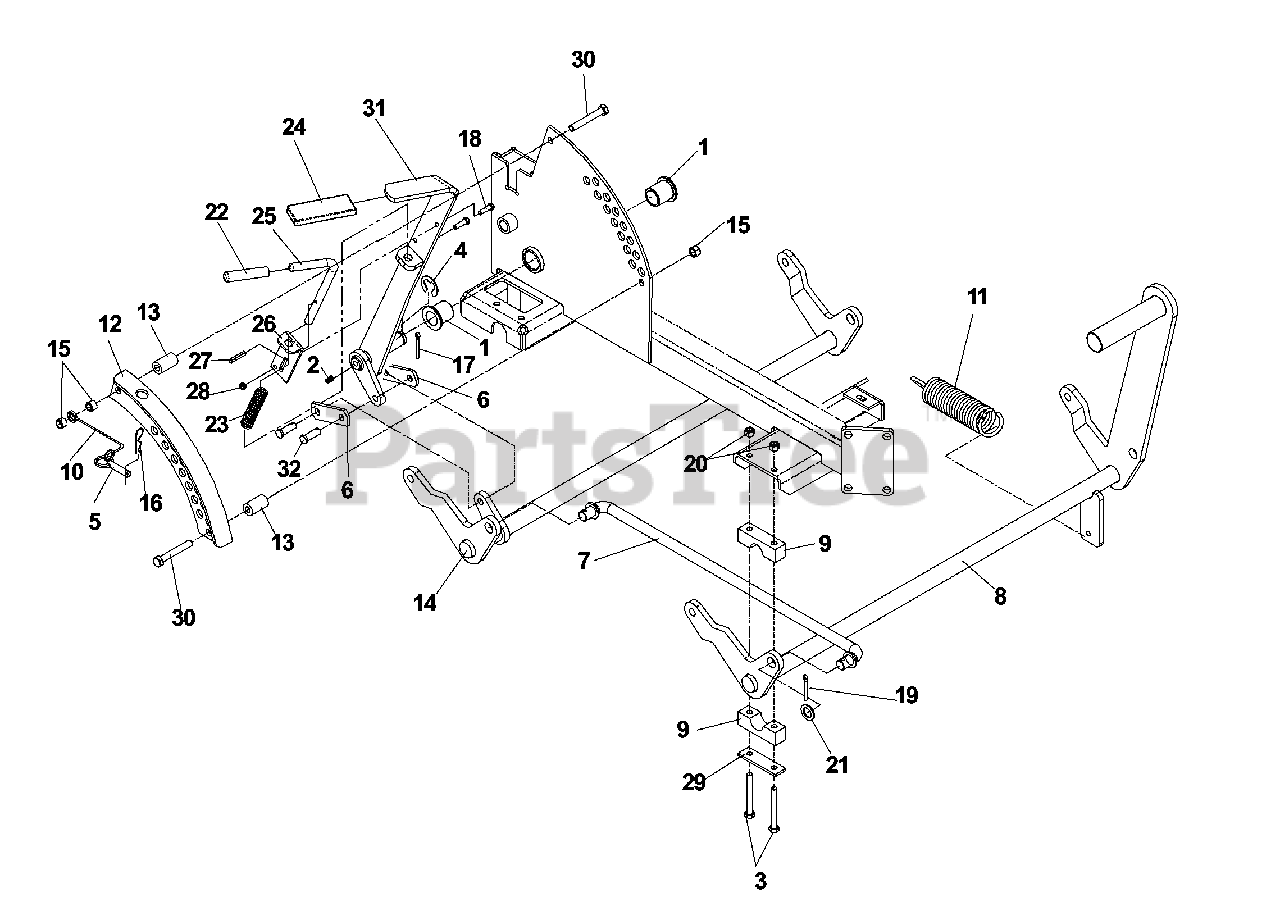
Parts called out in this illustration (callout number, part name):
1	BUSHING, FLANGED
3	HCS 5/16C X 2-3/4
4	E-RING 7/8
5	HITCH PIN
6	LIFT ARM
7	CROSS LINK
8	SHAFT, LIFT-FRONT
9	PILLOW BLOCK
10	LANYARD
12	ADJUSTMENT PLATE WLDMT
13	DECK LIFT SPACER
14	SHAFT, LIFT-REAR
15	NUT 3/8-16 NYLOC
16	HAIRPIN #4
17	COTTER PIN 1/8 X 3/4
18	HCS 1/4C X 3/4 HCS
19	COTTER PIN
20	NUT 5/16 NYLOC
21	BUSHING
26	PIN MT, UPPER
27	ROLL PIN
28	NUT 1/4C CENTER LOCK
29	REINFORCEMENT BAR
30	HCS 3/8C X 2 1/2
31	LIFT LEVER WELDMENT
32	CLEVIS PIN 3/8 X 1 1/8
